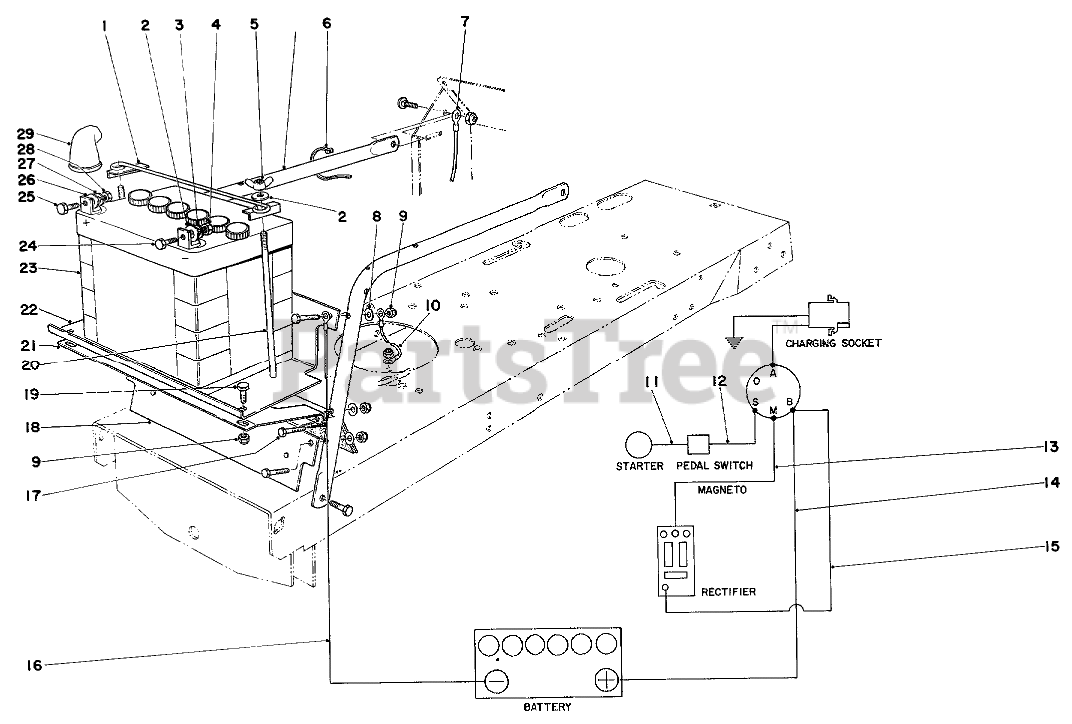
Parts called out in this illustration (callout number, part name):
1	Clamp
2	WASHER-FLAT
3	WASHER-LOCK
4	NUT-HEX
5	WING NUT
6	Cable Tie
7	Wire Assembly
8	WASHER
9	NUT-LOCK, CONE
10	ENG-GROUND WIRE ASM
11	Wire Assy. Switch to Starter
12	Wire-Starter Switch to Pedal Switch
13	Wire Switch to Mag.
15	Wire Switch to Battery
16	Wire Assembly
17	SCREW-HH
18	Heat Shield
19	SCREW-HH
20	BATTERY BOLT
21	Heat Shield
22	Battery Shelf
23	Battery
24	SCREW-HH
25	SCREW-HH
26	WASHER-PLAIN
27	WASHER-LOCK/SP
28	NUT-HEX
29	BATTERY BOOT
